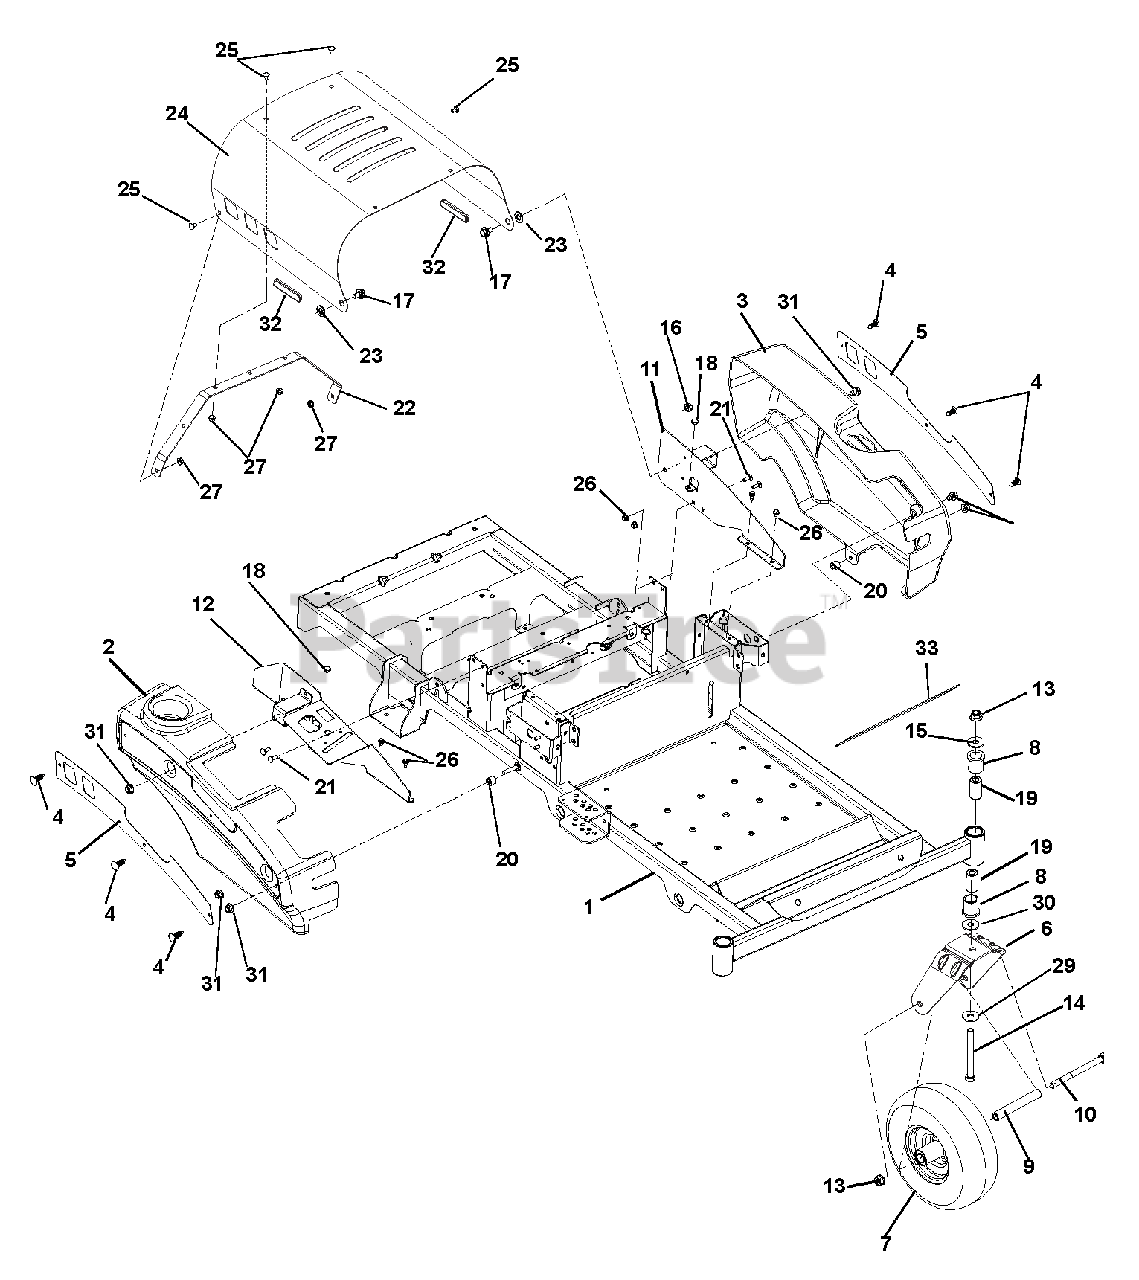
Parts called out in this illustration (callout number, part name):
1	WMT, BBZ FRAME
2	FENDER, RH
3	FENDER, LH
4	RIVET, .25 NYLON PANEL
5	PLATE, FENDER
6	CASTER FORK
7	TIRE/WHL ASM, FRONT
8	BSHG-FLG 1.00X1.25X1.50X1.50
9	SPACER, ROLLED WHEEL
10	@BLT-HEX .50-13X6.50 GR5 YWZC
11	WMT-RH FENDER BRKT
12	WMT-RH FENDER BRKT
13	@NUT-LK-TOP-FLG .50-13 YWZC
14	@BLT-HEX .50-13X5.00 GR5 YWZC
15	WSHR-FL-STL.511X1.441X.125 YWZ
16	@NUT-LK-TOP-FLG .38-16 YWZC
17	BOLT-SHLDR .375-16X.150
18	BUMPER GROMMET
19	SPACER, CASTER .50X1.00X1.84
20	BSHG-SLV .391X.688X.52 PM
21	@BLT-RDHDSQNK .25-20X.75 G5YZ
22	HOOD BRACE
23	WSHR-FL-NYL .518X1.000X.080
24	HOOD, BBZ
25	HOOD, BBZ
26	@NUT-LK-NYL-FLG .25-20 YWZC
27	@SCR-TAP .25-20X.50 HWH TR YWZ
28	@NUT-LK-TOP-FLG .25-20 YWZC
29	WSHR-FL-STL .515X1.625X.250 YZ
30	WSHR-FL-STL .518X2.0X.105 YWZC
31	@NUT-LK-NYL-FLG .31-18 YWZC
32	EDGING, CLUTCH PADDLE - 2.00"
33	GRIP, ADHESIVE (1" X 16" BLK)
